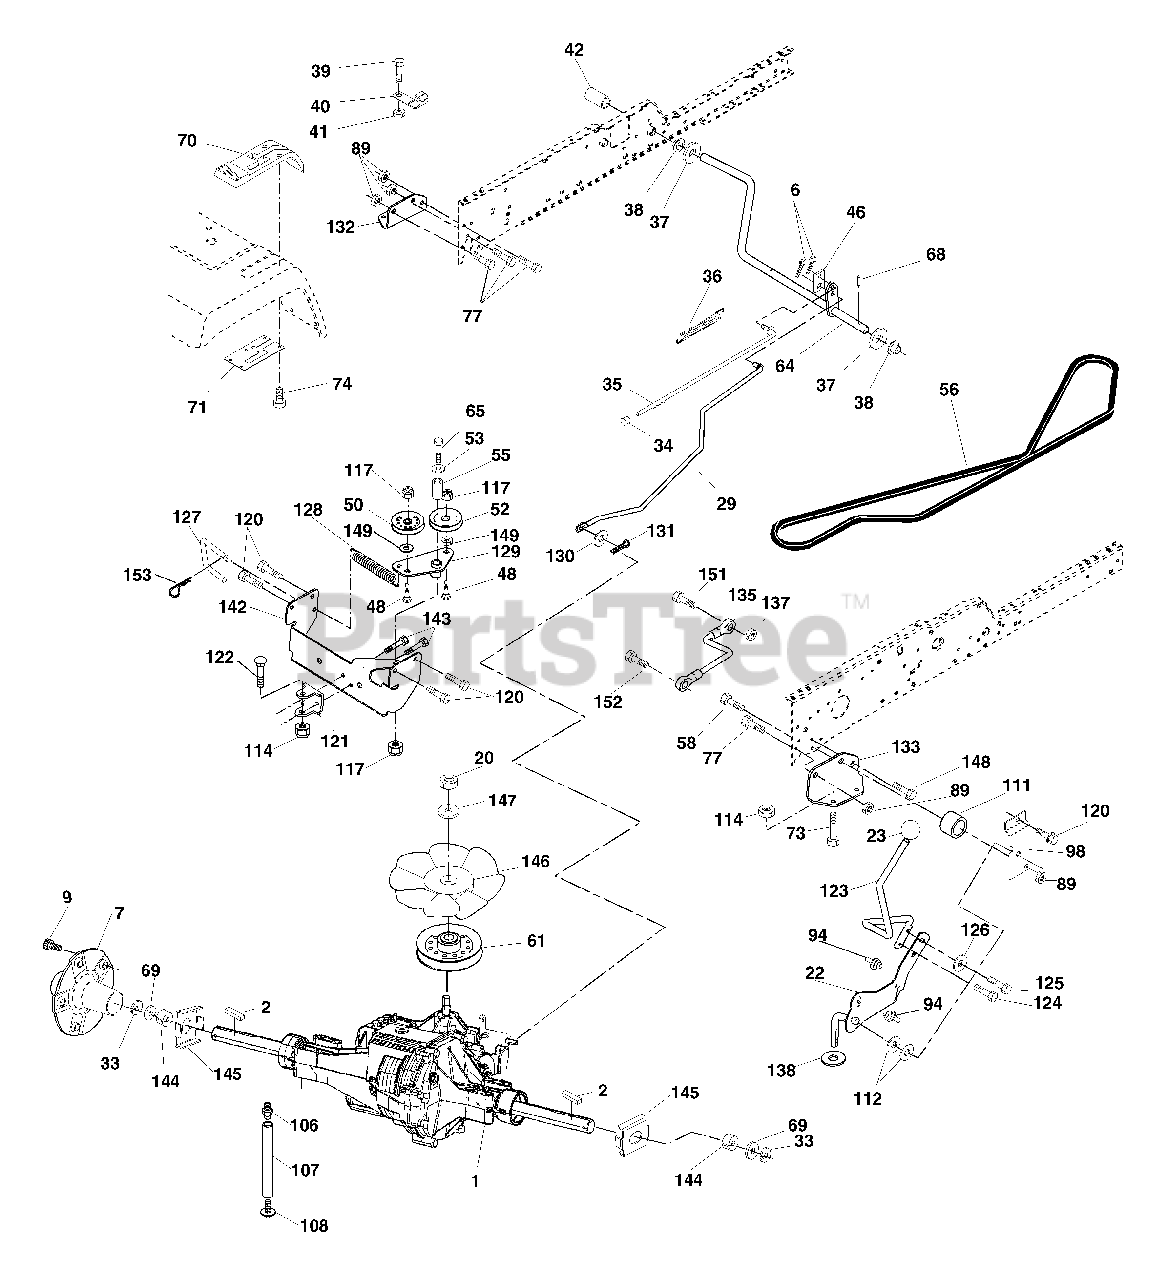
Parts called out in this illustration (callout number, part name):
2	Key Sq. 1/4 x 1/4 x 2
6	Pin, Cotter
7	Wheel, Hub Assembly
9	Bolt, Hub
20	Nut
22	Lever Asm Shift
23	Knob
29	Brake, Rod
33	Ring E
34	Cap, Parking Brake
35	Rod, Parking Brake
36	Spring, Drive Ground
37	Washer 25/32 x 1-1/4 x 16 Ga.
38	Nyliner
39	Screw, Fin. #10-24 x 1
40	Actuator, Interlock
41	Nut Centerlock 10-24 Unc
42	Cover, Pedal
46	Retainer,Spring
48	Bolt Carr. Shoulder 3/8-16 x 1-3/4 Gr. 5
50	Pulley, Idler, Flat
52	Pulley, Idler, Grooved
53	Washer,Hardened
55	Bearing, Idler
56	V-Belt
58	Bolt Fin Hex 7/16-14 x 1-1/2
61	Pulley, Transaxle
64	Shaft, Brake Pedal
65	Bolt, Shoulder
68	Pin, Roll
71	Plate Console Shift
73	Bolt Hex Flghd 5/16-18 x 3 Gr5
74	Screw Hex Wsh. Hi-Lo 1/4-1/2
77	Bolt Fin Hex 7/16-14 x 1
89	Nut Crownlock 7/16-14 Unc
94	Fastener Christmas Tree
98	Bracket Shift
106	O-Ring Asm Hydro Gear
107	Line Fuel Hydro 15" VGT
108	Cap Asm Vent Hydro Gear
111	Spacer Shift Lever VGTH
112	Washer Nylon High Temp
114	Nut Lock Hex W/Ins 5/16-18 Unc
117	Nut, Lock Flg. 3/8-16
120	Screw 3/8-16 x .75
121	Bracket Strap Torque
122	Bolt 5/16-18 x 2.50
123	Rod Shift
124	Bolt Shoulder 5/16-18 x .561
125	Screw 5/16-18 x 5/8
126	Washer SRRTD 5/16 ID x 1.0 x .125
127	Link Control Clutch
128	Spring Drive GRND
129	Bracket Asm Idler Tensioning
130	Washer 13/32 x 5/8 x 16 Ga.
131	Pin Cotter 3/32 x 3/4
132	Bracket Mtg Hydro 3500 LH VGT
133	Bracket Mtg Hydro 3500 RH VGT
135	Link Asm Control Hydro 3500
137	Nut Lock 5/16-18 NC Thd.
138	Washer Thrust 5/8 x 1.10 x 1/32
142	Strap Torque HG-3500
143	Screw 5/16-18 x 3/4
144	Washer Spacer Axle HG-3000
145	Washer Axle Flange HG-3000
146	Fan 7" Hydro
147	Washer
148	Screw 3/8-16 x 1.0
149	Washer 13/32 x 7/8 x 10 Ga.
151	Bolt Fin Hex 5/16-18 x 7/8
152	Bolt Hex 5/16-18 x 1 w/Patch
153	Spring,Retainer
